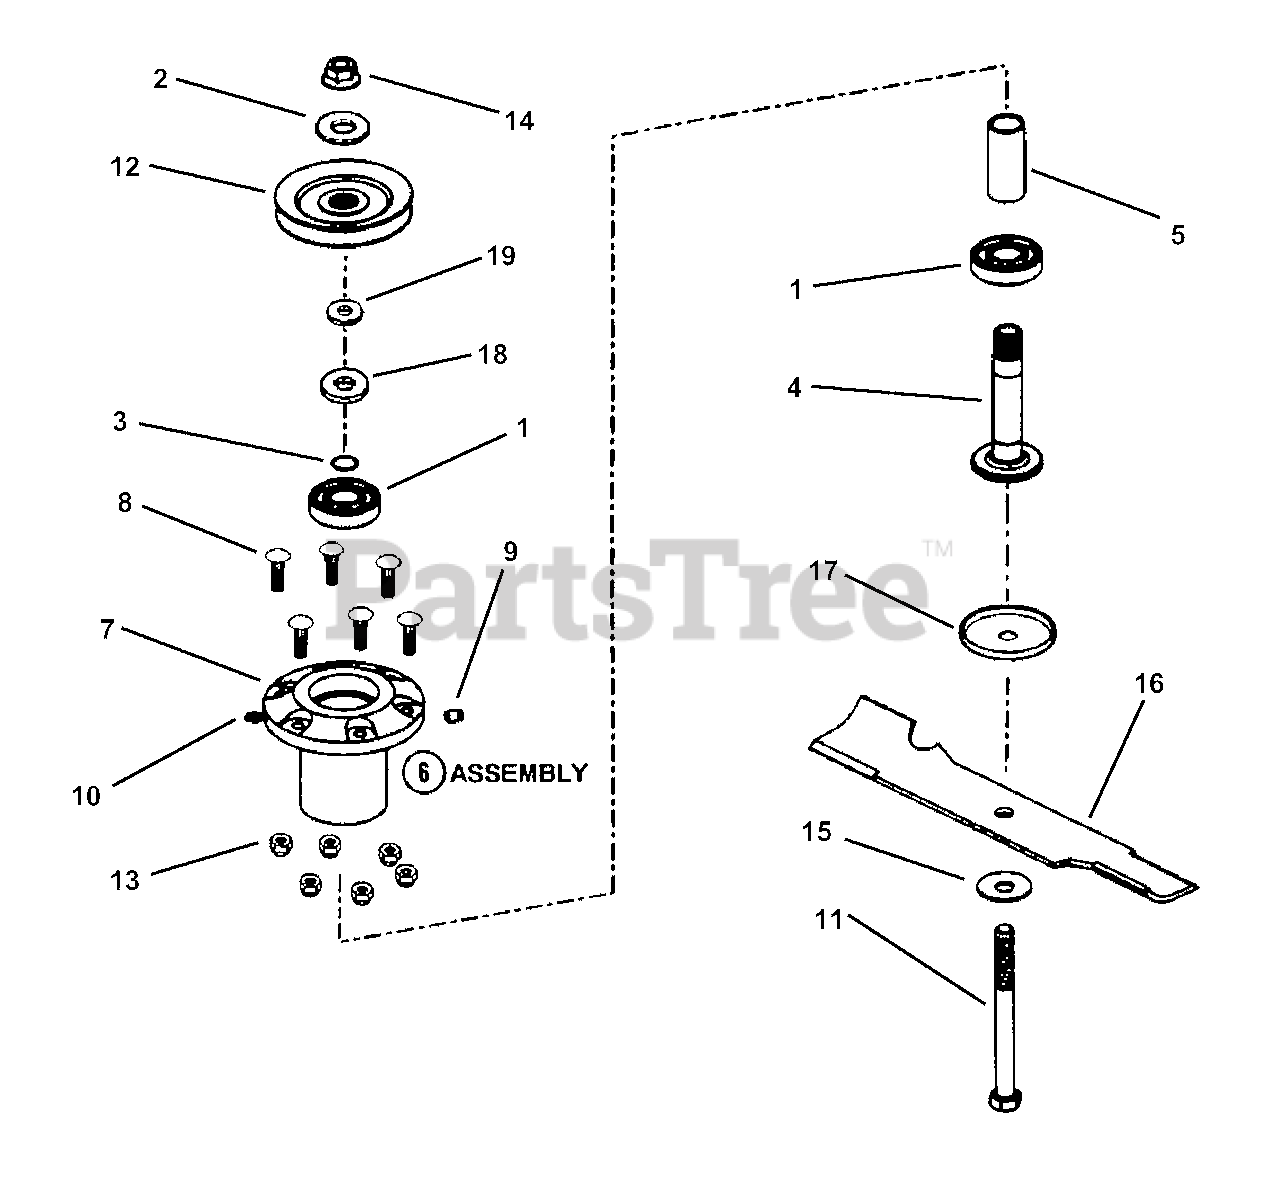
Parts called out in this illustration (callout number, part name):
1	BEARING, Sealed
2	WASHER, Spindle
3	SNAP-RING, Spindle Shaft
4	SHAFT, Spindle
5	SPACER, Bearing
6	ASSEMBLY, Housing
7	HOUSING, Spindle
8	BOLT, 3/8-16 x 1-1/4" Rib Necked
9	VENT, Spindle
10	LUBE FITTING, 1/4-28 Thread Forming
11	BOLT, Blade 5/8-11 x 7" Hex Head, Grade 5
12	PULLEY, 5-3/4" O.D.
13	NUT, 3/8-16 Hex Nyloc
14	NUT, 5/8-11 Hex Flange Lock, Grade 5
15	WASHER, Beveled
16	BLADE, 16-5/16"
17	CUP, Spindle Cover
18	SEAL, Nylos
19	WASHER
